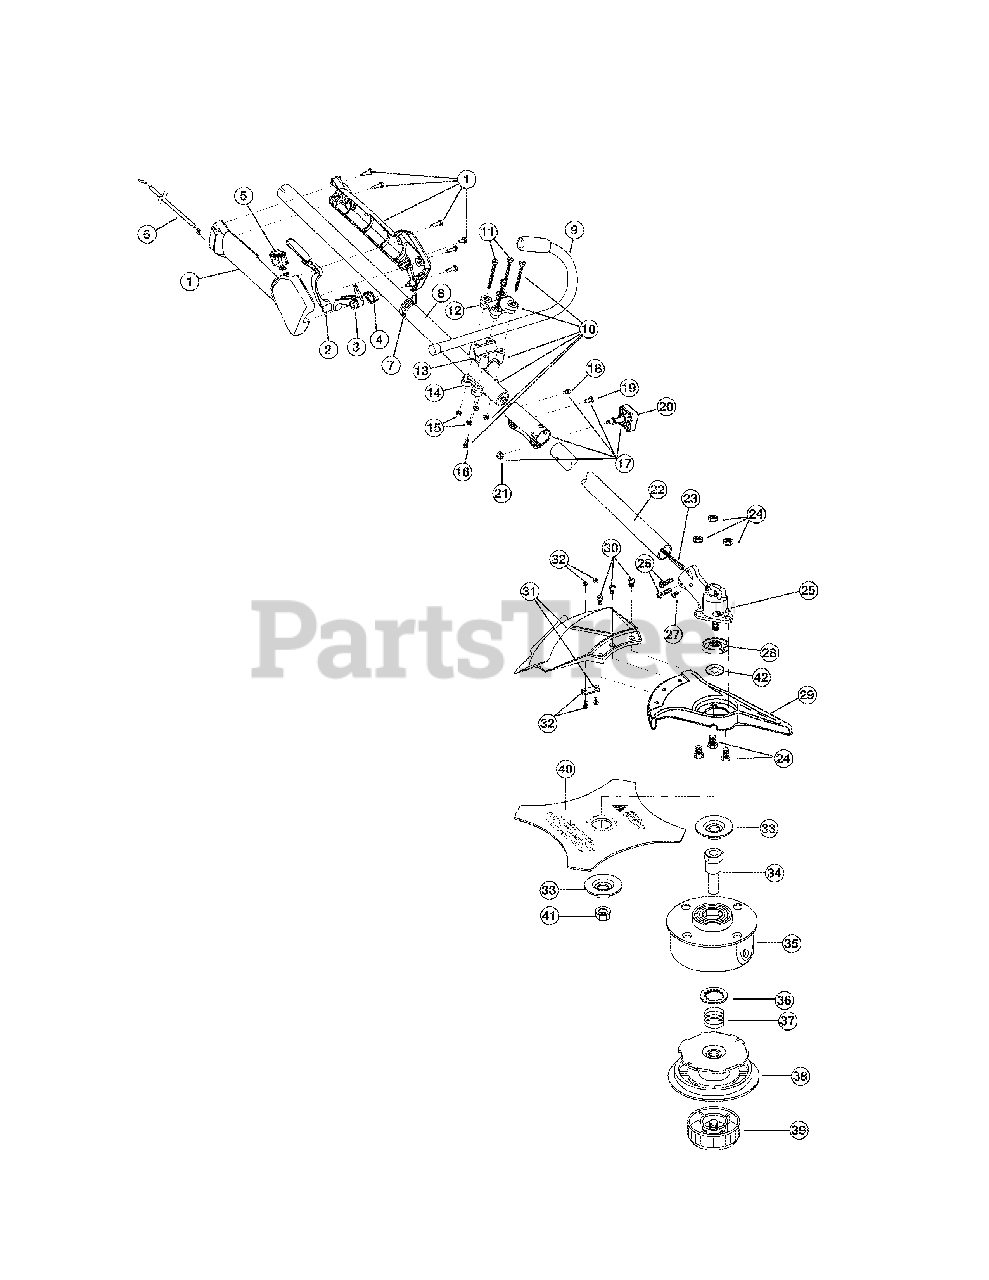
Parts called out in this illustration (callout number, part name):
1	Throttle Housing Assembly (includes 2-4)
2	Throttle Trigger Lock-Out
3	Throttle Trigger
4	Throttle Trigger Spring
5	Switch Assembly
6	Throttle Cable
7	Harness Clip
8	Upper Drive Shaft Housing Assembly
9	J-Handle Assembly
10	Handle Bracket Assembly (includes 11-16)
12	Upper Handle Clamp
13	Middle Handle Clamp
14	Lower Handle Clamp
16	Anti-Rotation Screw
17	Split Boom Coupler (includes 18-21)
20	Adjustment Knob
21	Knob Retaining Nut
22	Lower Drive Shaft Housing Assembly
23	Lower Flexible Drive Shaft
24	Shield Mount Screw Assembly
25	2 piece Gearbox Assembly (includes 26-28 & 42)
26	Gearbox Mounting Hardware
27	Anti-Rotation Screw
28	Blade Driver
29	Blade Shield/Shield Mount
30	Shield Mounting Screw
31	Shield and Blade Assembly (includes 32)
32	Blade Assembly
33	Retaining Washer
34	Spool Shaft
35	Outer Spool Assembly (includes 36)
36	Retainer
38	Inner Reel
39	Bump Head Knob Assembly
40	4-Tooth Blade
41	Nut
42	Palnut
